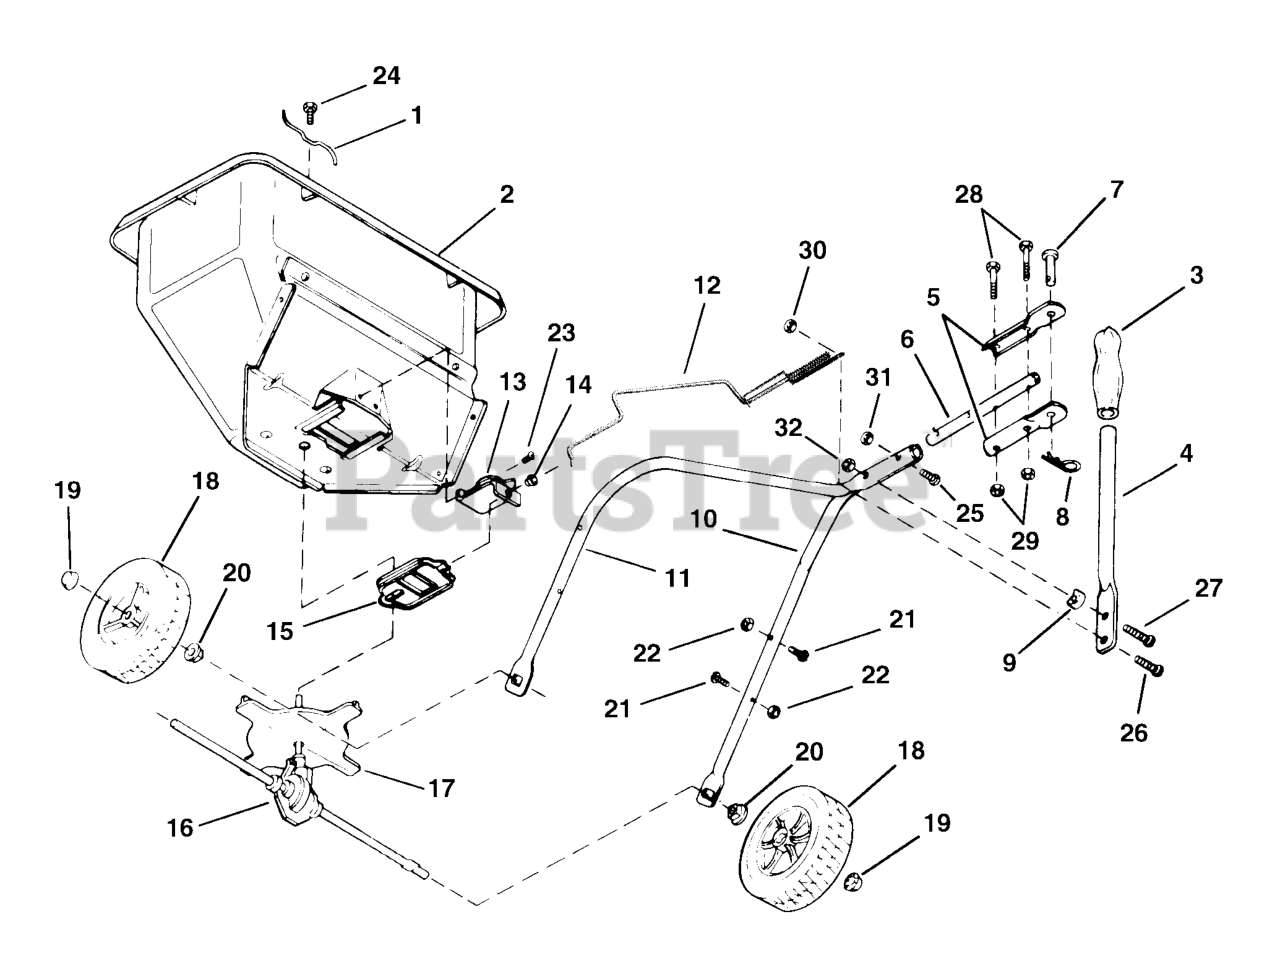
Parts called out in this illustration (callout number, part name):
22	LOCKNUT M5
28	Hex Head Capscrew, M6 X 1.00 X 40MM
31	LOCKNUT M5
